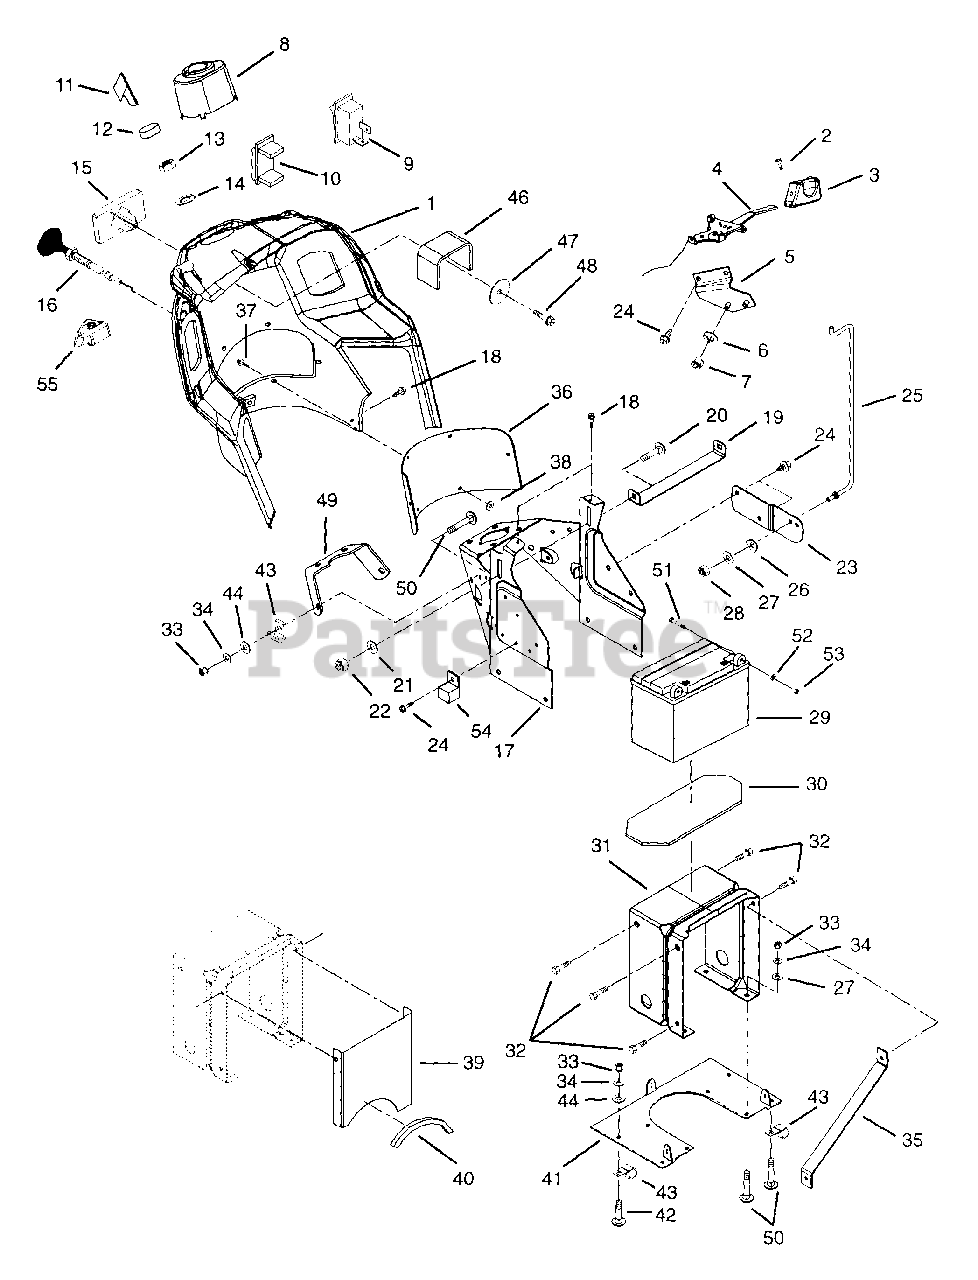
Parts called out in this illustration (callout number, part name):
2	SCR-SET 10-24X.38 UNC-3A
3	KNOB - THROTTLE
4	THROTTLE CONTROL-B&S
5	BRACE-THROTTLE CONTROL
6	WSHR-FL-STL .323X.625X.062 PL
7	NUT-LK-CTR .250-20 PL
8	STEERING CONE
9	SWITCH - LIGHT
10	COVER - SWITCH
11	KEY -W/CAP
12	CAP - IGNITION SWITCH
13	NUT- PANEL .562-24 GRECO
14	WSHR-LK-INT .563X.040 PL
15	KNOB - FILLER
16	CHOKE CABLE
17	SUPPORT - DASH - TOP
18	SCR-TAP 10-24X.484 HWH TR
19	HOLDDOWN - BATTERY
20	BLT-RDHDSQNK .312-18X.62 PL
21	WSHR-FL-STL .323X.625X.062 PL
22	NUT-LK .312-18 GR A PL
23	MOUNT - PROP ROD
24	SCR-TAP .250-20X.37 HWH PL TR
25	ROD - HOOD PROP
26	WAVE WASHER .390X.655X.110
27	WSHR-FL-STL.312X.734X.065PL
28	NUT-LK-CTR .250-20 PL
29	BATTERY
30	RUBBER PAD
31	SUPPORT DASH BASE
32	SCR-TAP .312-18X.50 HWH PL TR
33	NUT-HEX .312-18
34	WSHR-LK .312X.097 PL HVY
36	SCREEN - DASH
37	RETAINER, RADIATOR SHROUD
38	WSHR-FL-STL .265X.500X.087 PL
39	SHIELD, AIR
40	TAPE-ADHESIVE BACKED FOAM
41	SUPPORT, DASH BASE (G.S. ONLY)
42	BLT-RDHDSQNK .31-18X.75 GR5 PL
43	J-CLAMP
44	WSHR-FL-STL.344X.688X.065PL
45	KNOB - FILLER
46	SPACER-CHANNEL
47	WSHR-FL-STL .281X1.250X.048 BL
48	SCR-TAP .250-20X.75 HWH PL TR
50	BLT-HEX .31-18X.75 PL GR2
51	BLT-HEX .25-20X.75 PL GR5
52	WSHR-LK .250X.077 HVY PL
53	NUT-HEX .250-20 PL
54	RELAY
55	PTO KNOB/ SWITCH ASSY
